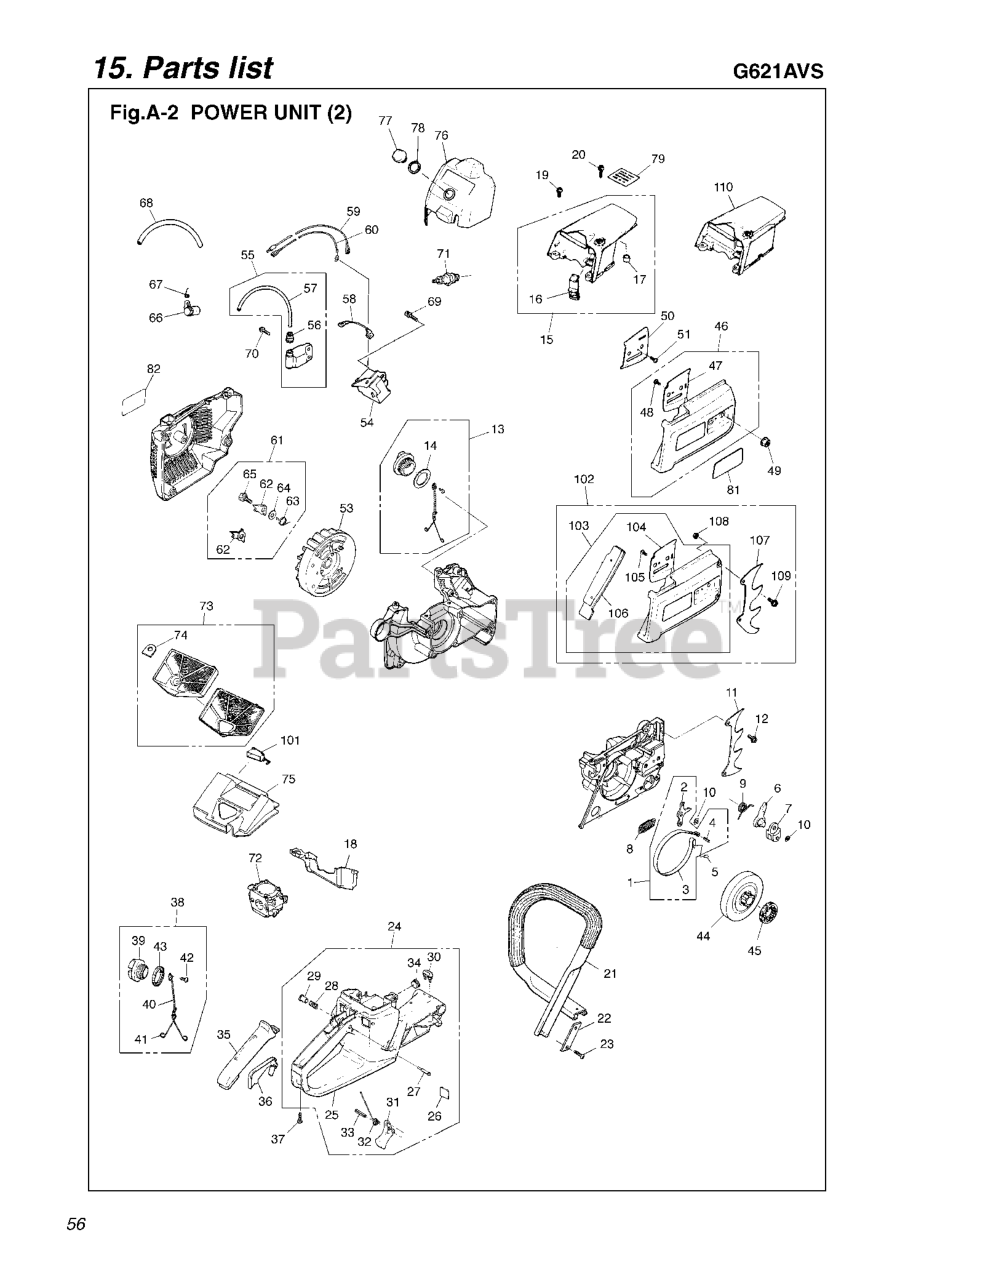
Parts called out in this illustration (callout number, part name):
1	BAND COMP
2	BAND.BRAKE
3	ARM.BRAKE
5	ROLLER
6	LEVER, BRAKE (RPLS 335624210)
7	STOPPER (RPLS 262224500)
15	COVER COMP (RPLS 261631103)
23	SCREW (RPLS 267132210)
24	R HANDLE ASSY(RPL-33002,33000)
25	HANDLE (RPLS -33104,-33102)
31	LEVER (RPLS 335633312)
33	SPRING PIN
34	DAMPER(B)
36	ARM (RPLS 335633350-335633352)
46	COVER, CHAIN (RPLS 3356-53002)
49	NUT FLANGE
51	SCREW, M4 X 10
53	ROTOR (RPLS 261671110)
54	RESOURCE COIL(RPLS 261671210)
56	CAP
67	SPRING PLUG
73	CLEANER, AIR (RPLS 335698200)
75	SILENCER
76	COVER (RPLS -83301,-83300)
77	KNOB Z335683322
79	LABEL.WARNING
102	DOUBLE SPIKE KIT
103	CHAIN COVER
105	SCREW, M4 X 10
109	RP_SCREW
